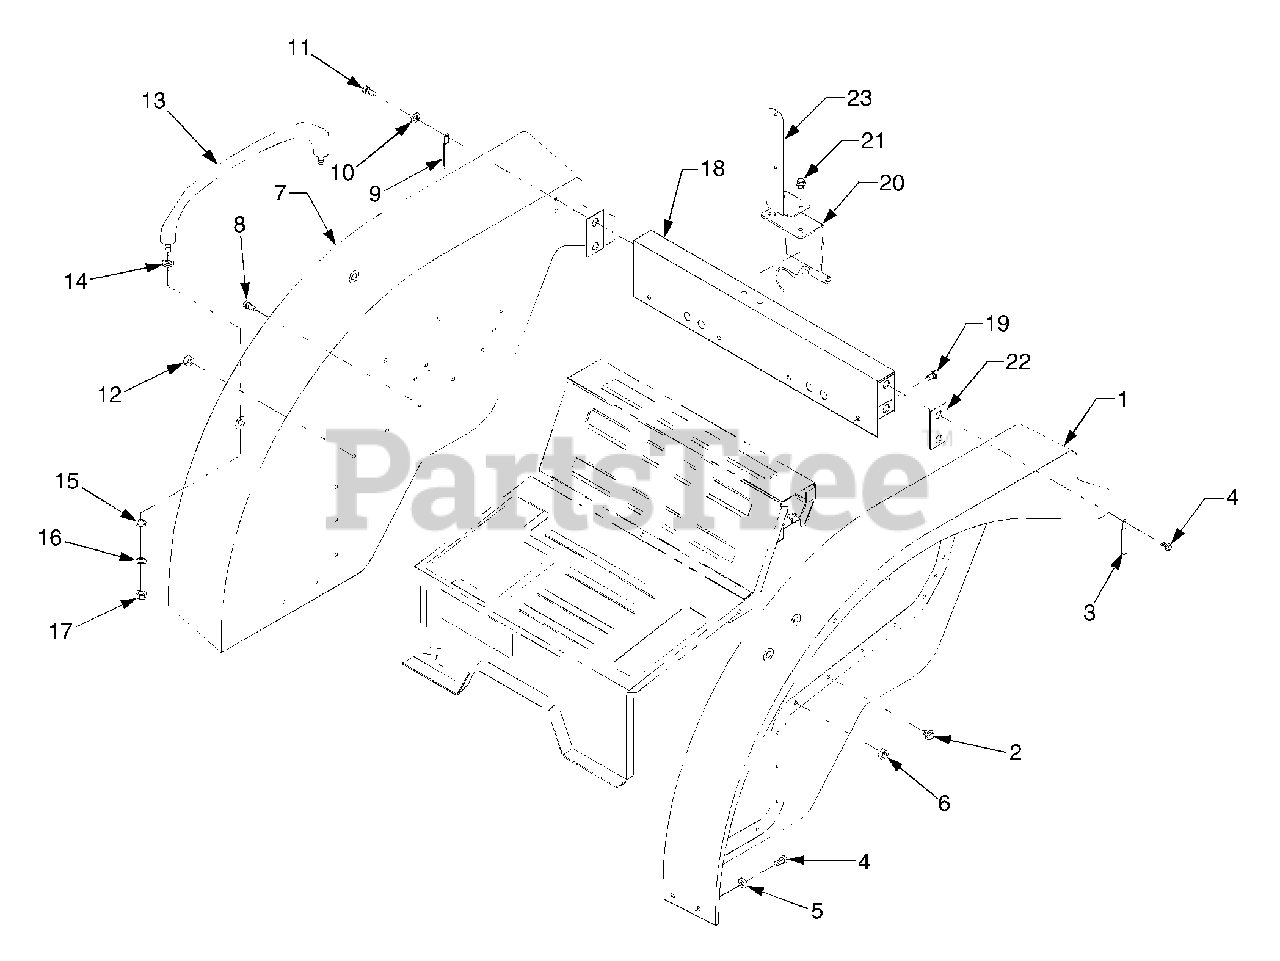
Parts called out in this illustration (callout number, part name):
1	Fender (LH) Ass'y
5	Washer, Plain
7	Fender (RH) Ass'y
11	Washer, Plain
15	Washer, Plain
16	Washer, Spring
18	Support, Fender
20	Hook, Top Link
